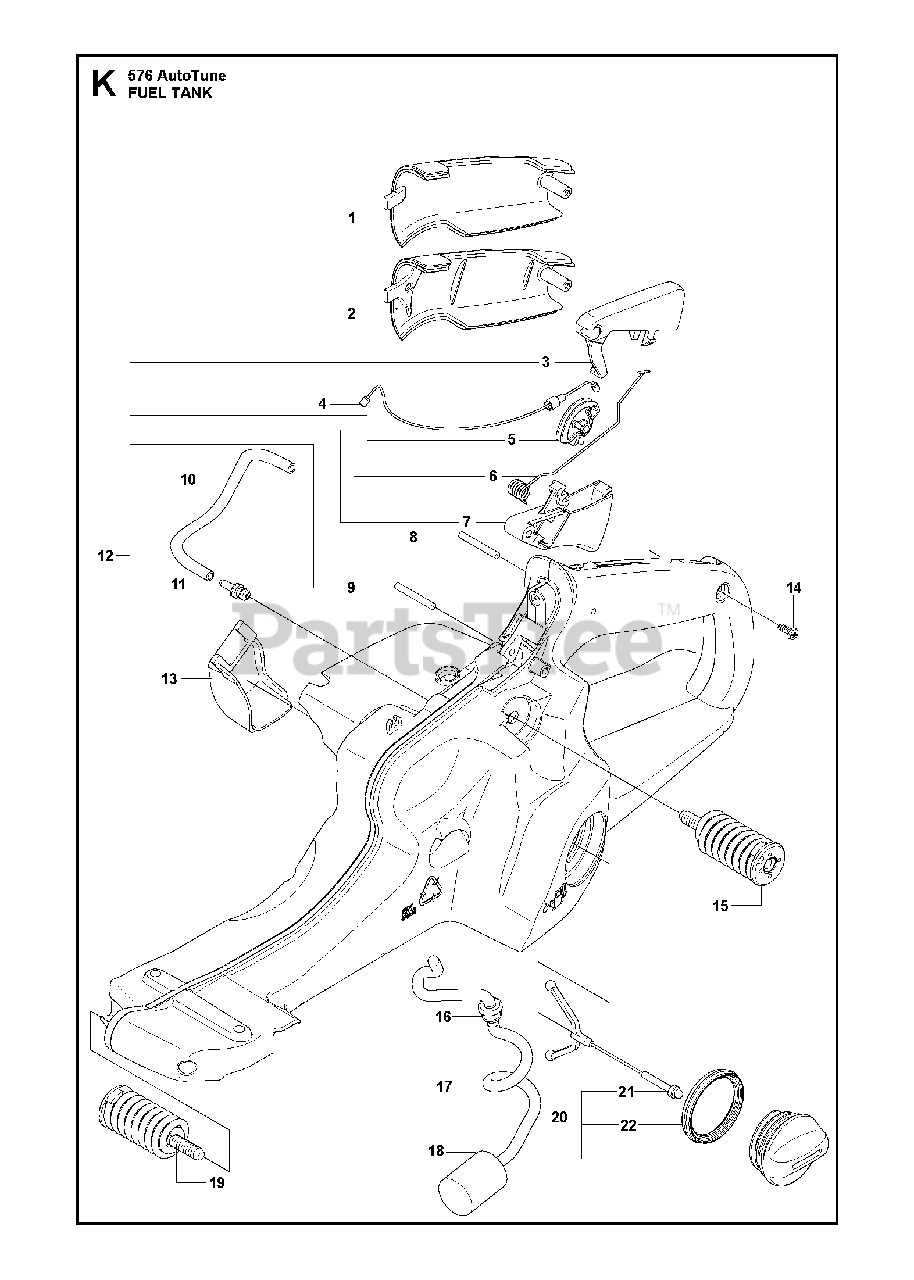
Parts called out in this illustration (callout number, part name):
1	COVER
2	COVER
3	THROTTLE LOCK
4	THROTTLE WIRE
5	LEVER
6	SPRING
7	THROTTLE TRIGGER
8	PIN 3X25
9	PIN 3X25
10	HOSE
11	FUEL TANK VENT
15	VIBRATION ABSORBER
16	FUEL TANK BUSHING
17	FUEL HOSE
18	FUEL FILTER
19	VIBRATION ABSORBER
20	TANK CAP
21	TANK LOCK
22	SEALING
